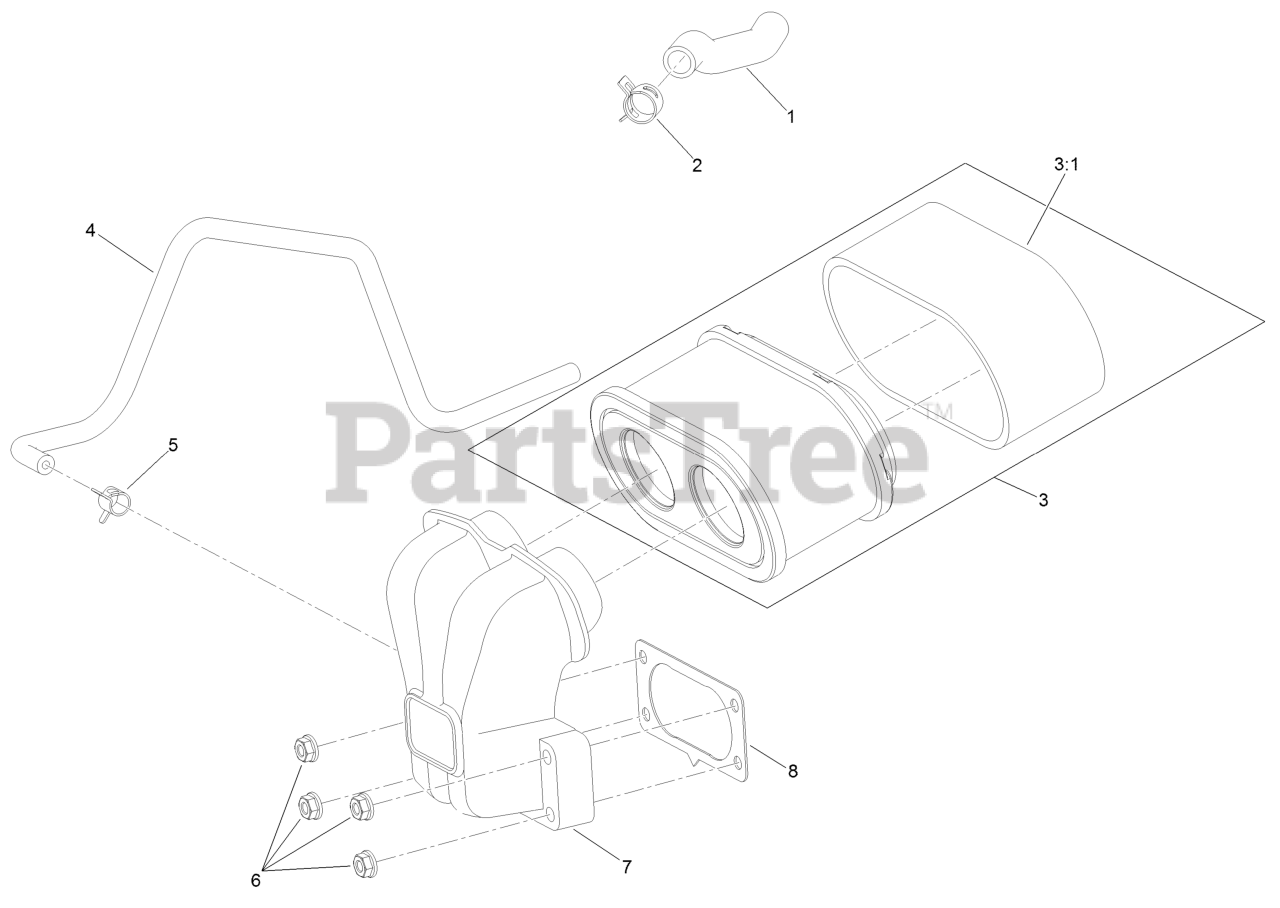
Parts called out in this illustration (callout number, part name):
1	TUBE-BREATHER
2	CLAMP-HOSE
3	AIR FILTER KIT
3:1	PREFILTER
4	HOSE-FUEL
5	CLAMP-HOSE
6	NUT-FLANGE
7	MANIFOLD-FILTER, AIR
8	GASKET-CARBURETOR
